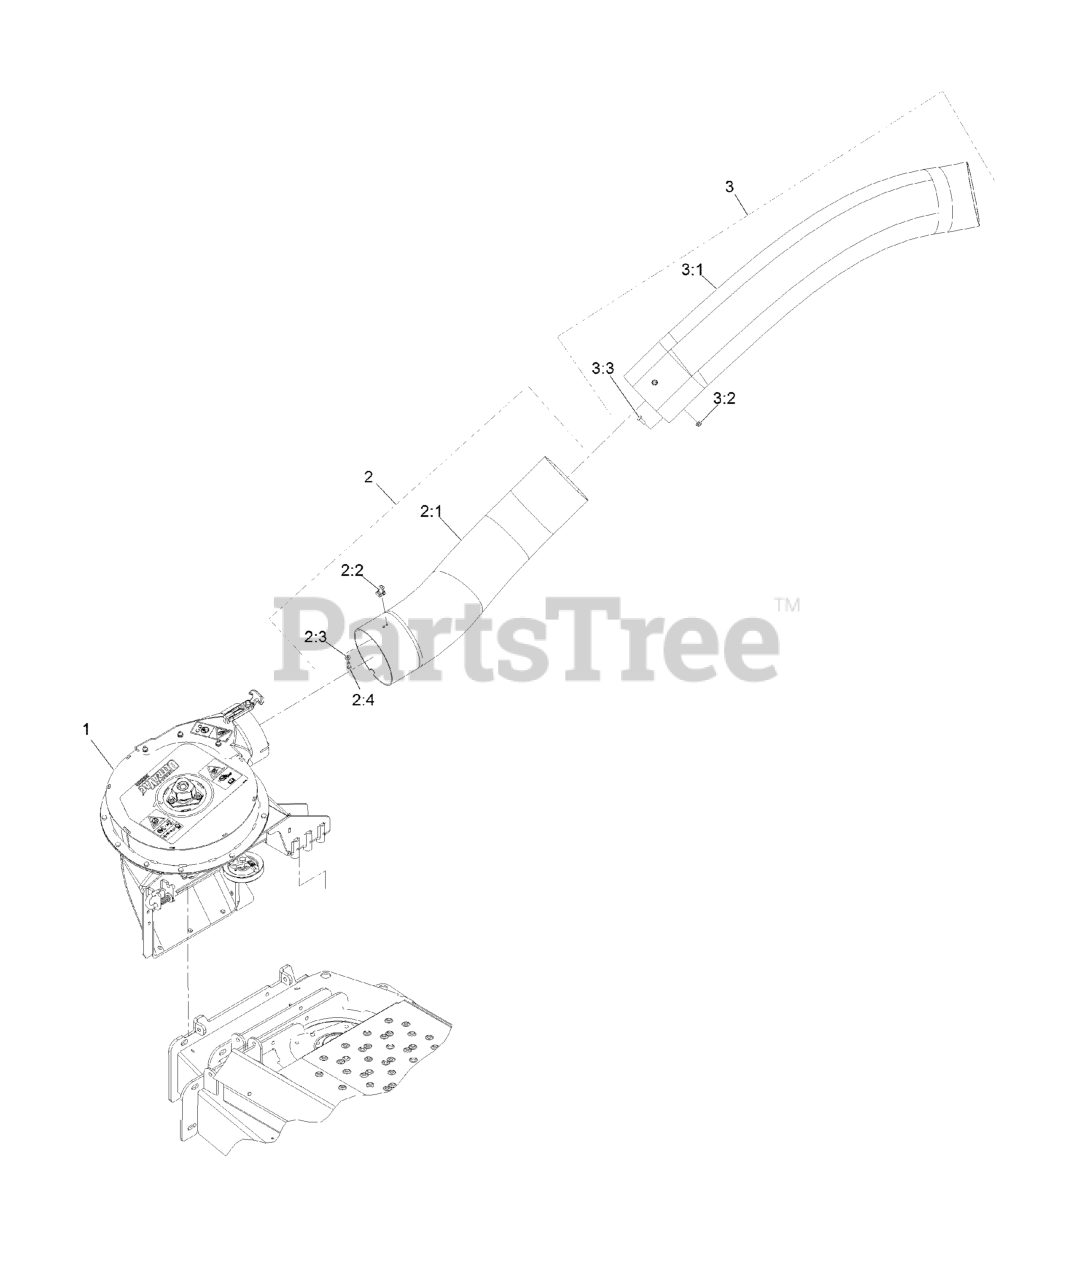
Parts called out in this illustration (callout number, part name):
1	ASM-BLOWER UV E SERVICE
2	LOWER TUBE ASM
2:1	TUBE-LOWER
2:2	LATCH-KEEPER
2:3	WASHER-FLAT
2:4	SCREW-PPH
3	UPPER TUBE ASM
3:1	TUBE-UPPER
